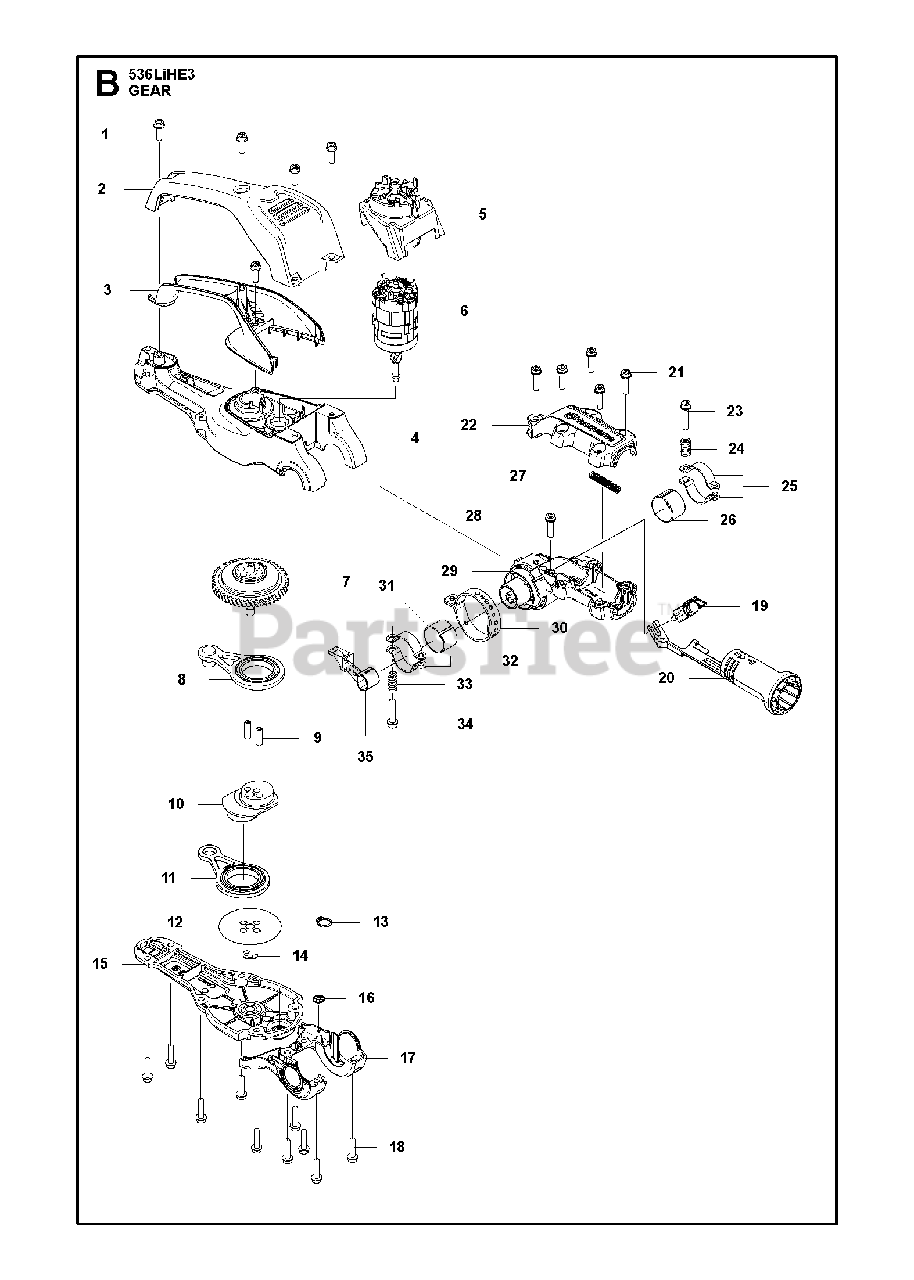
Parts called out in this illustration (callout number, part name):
1	Screw, Ihscft
2	MOTOR COVER UPPER
3	MOTOR COVER LOWER
5	AIR CONDUCTOR MOTOR
6	MOTOR ASSY
8	CONNECTING ROD ASSY
9	HEAVY DUTY DOWEL PIN PROJEKT 1
10	ECCENTRIC DISC GEAR
11	CONNECTING ROD ASSY
12	WASHER DISK DISC
13	SEEGER CLIP
14	LOCK WASHER
15	COVER LID GEAR HOUSING ASSY
16	LOCK WASHER
17	BEARING CAP
18	SCREW IHSCFT
19	LOCKING PIN ASSY
20	Handle Grip
21	SCREW IHSCFT
24	BRAKE BAND
25	BRAKE BAND ASSY POLE HEDGETRIM
26	SLIDE RING
27	COMPRESSION SPRING
28	SCREW IHSCFT
29	HOUSING JOINT
30	RING INDEX
31	SLIDE RING
32	BRAKE BAND ASSY POLE HEDGETRIM
33	BRAKE BAND
